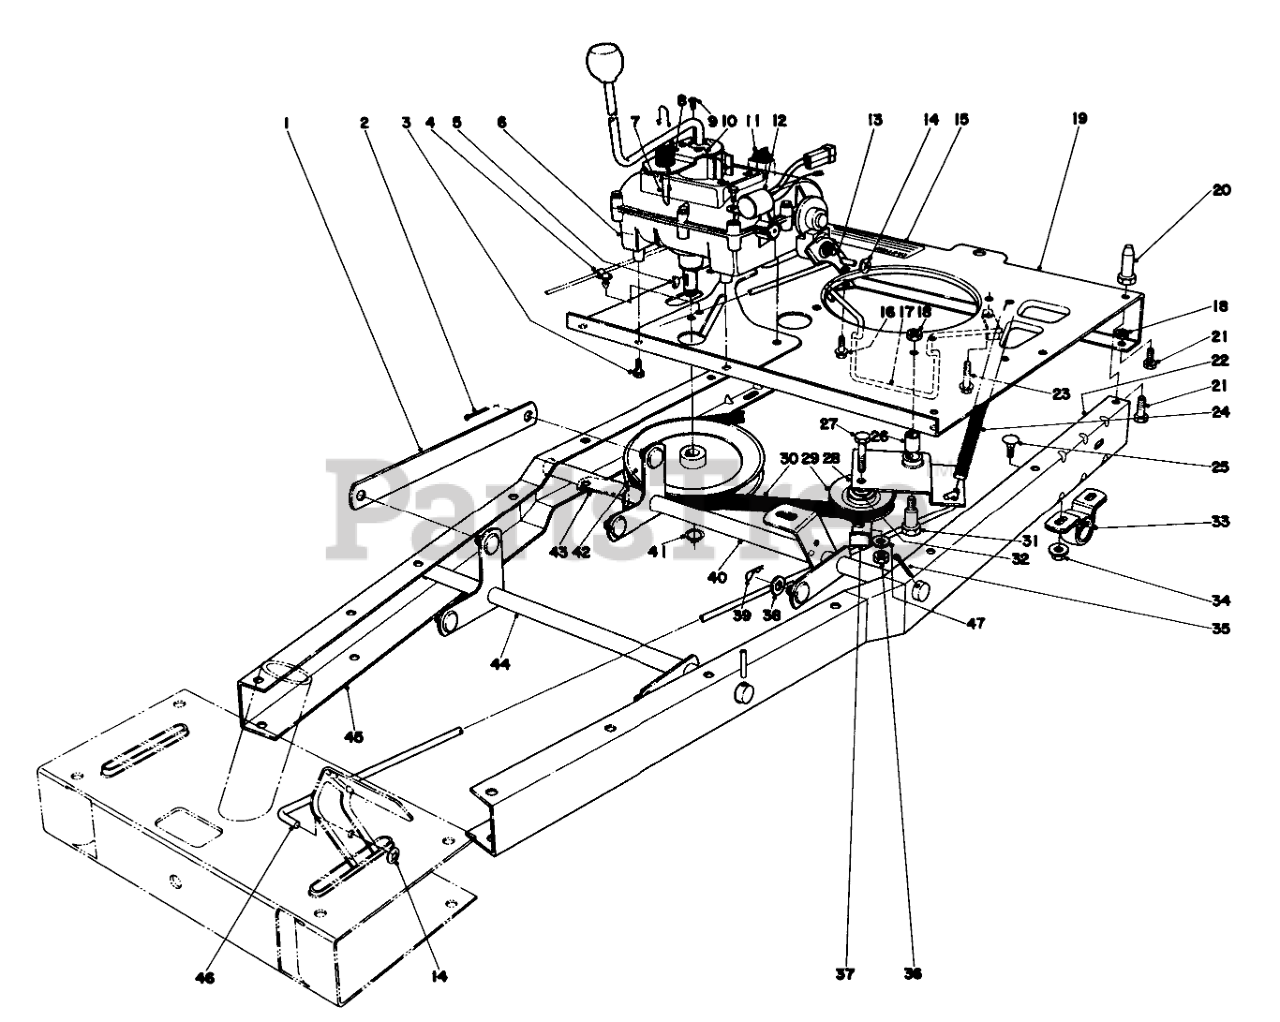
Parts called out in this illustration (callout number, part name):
1	Linkage-Height Adj.
2	PIN-COTTER
3	5/16-18 X 5/8 SEMS SC
4	Cable Holder
5	KEY-WOODRUFF
6	Transmission 3 Speed
7	Neutral Spring Wire
8	Compression Spring
9	SCREW-HEAD, PAN
10	Neutral Bracket
11	Wire & Cable Tie
12	Control Module
13	Brake Return Spring
14	PUSH ON SPEED NUT 1/4
15	Decal
16	SCREW-HWHTF
17	Belt Guide
18	NUT-LOCK, CONE
19	Plate-Engine Mounting
20	PIN-MOUNTING, LOWER
21	SCREW-HH
22	Frame Chanel, L.H.
23	Screw
24	Clutch Tension Spring
25	SCREW-CARR
26	BUSHING
27	SCREW-HH
28	Traction Idler (Incl. Ref. #26)
29	PULLEY-IDLER
30	V-BELT
31	CLUTCH PIVOT BOLT
32	WASHER-FLAT
33	PILLOW BLOCK
34	NUT-HF
35	PIN-COTTER
36	NUT-LOCK, CONE
37	RETAINER-BELT
38	WASHER-FLAT
39	PIN-COTTER
40	Height Adjustment
41	RING-SNAP, EXTERNAL
42	Pulley
43	TRANS BELT RET B
44	FRONT LIFT WA B
45	Frame Channel R.H.
46	Clutch Rod
47	Washer
